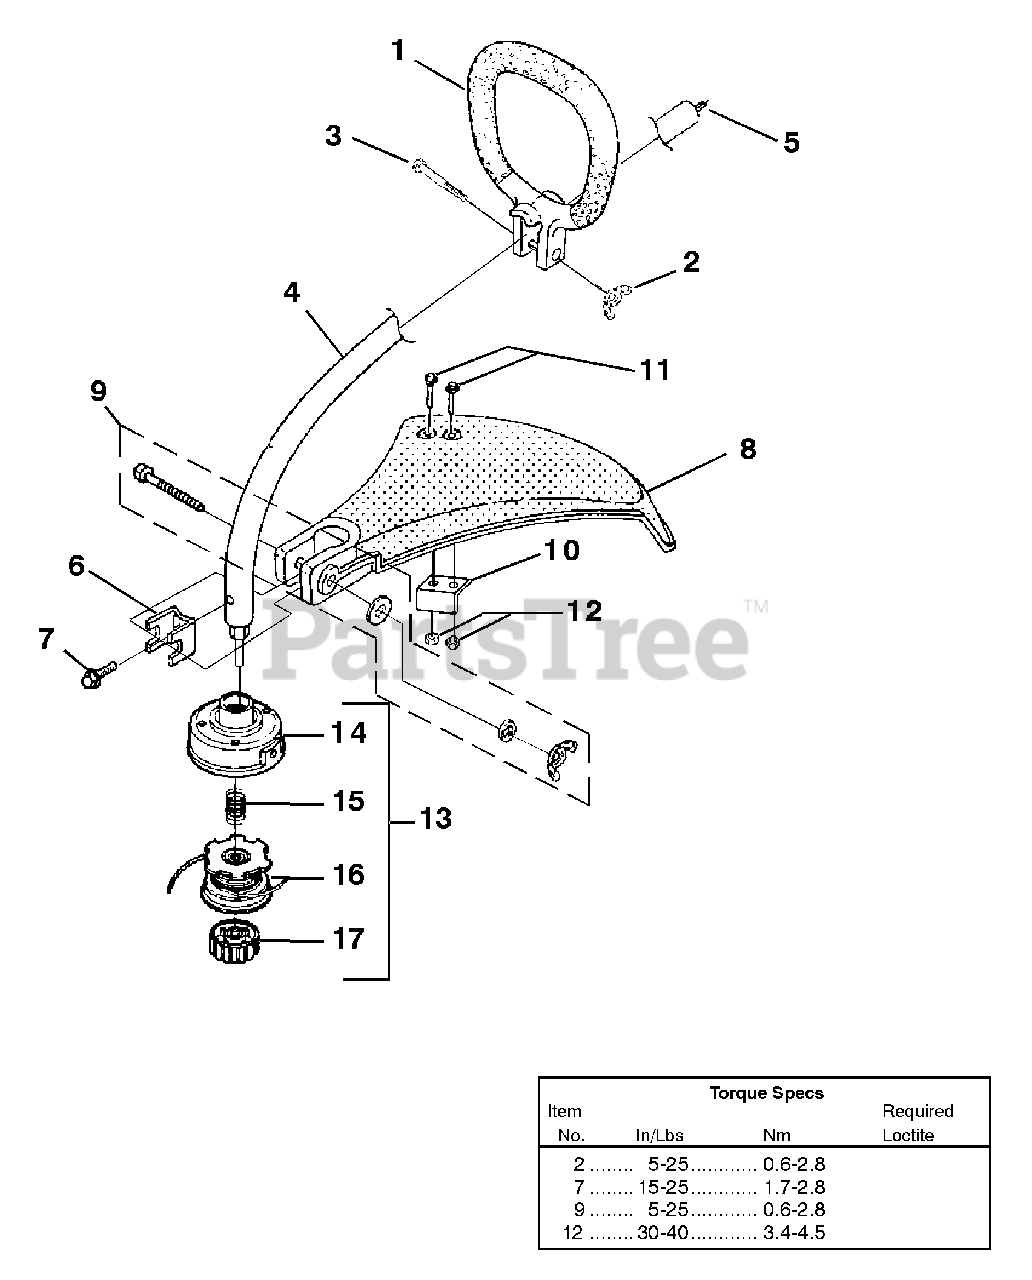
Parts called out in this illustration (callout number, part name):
1	HANDLE ASSY.-Front
2	NUT-Wing, Washer Faced (1/4-20)
3	SCREW-Cap Hex Hd.
4	DRIVESHAFT HOUSING ASSY.
5	SHAFT-Flexible
6	CLAMP
7	SCREW-T.F. Hex Hd. (#10-24 X 3/8")
8	DEFLECTOR & BLADE KIT (55 Deg.)
9	FASTENER Parts Kit
10	BLADE-Cut-Off
11	SCREW-Mech. Hex Hd. (10-24 X 7/8")
12	NUT-Hex (10-24)
13	STRINGHEAD-Complete
14	HOUSING & EYELET (Dual Line)
15	SPRING-Compression
16	SPOOL & STRING (.080" Line)
17	RETAINER-Spool (RH Thread, Black)
